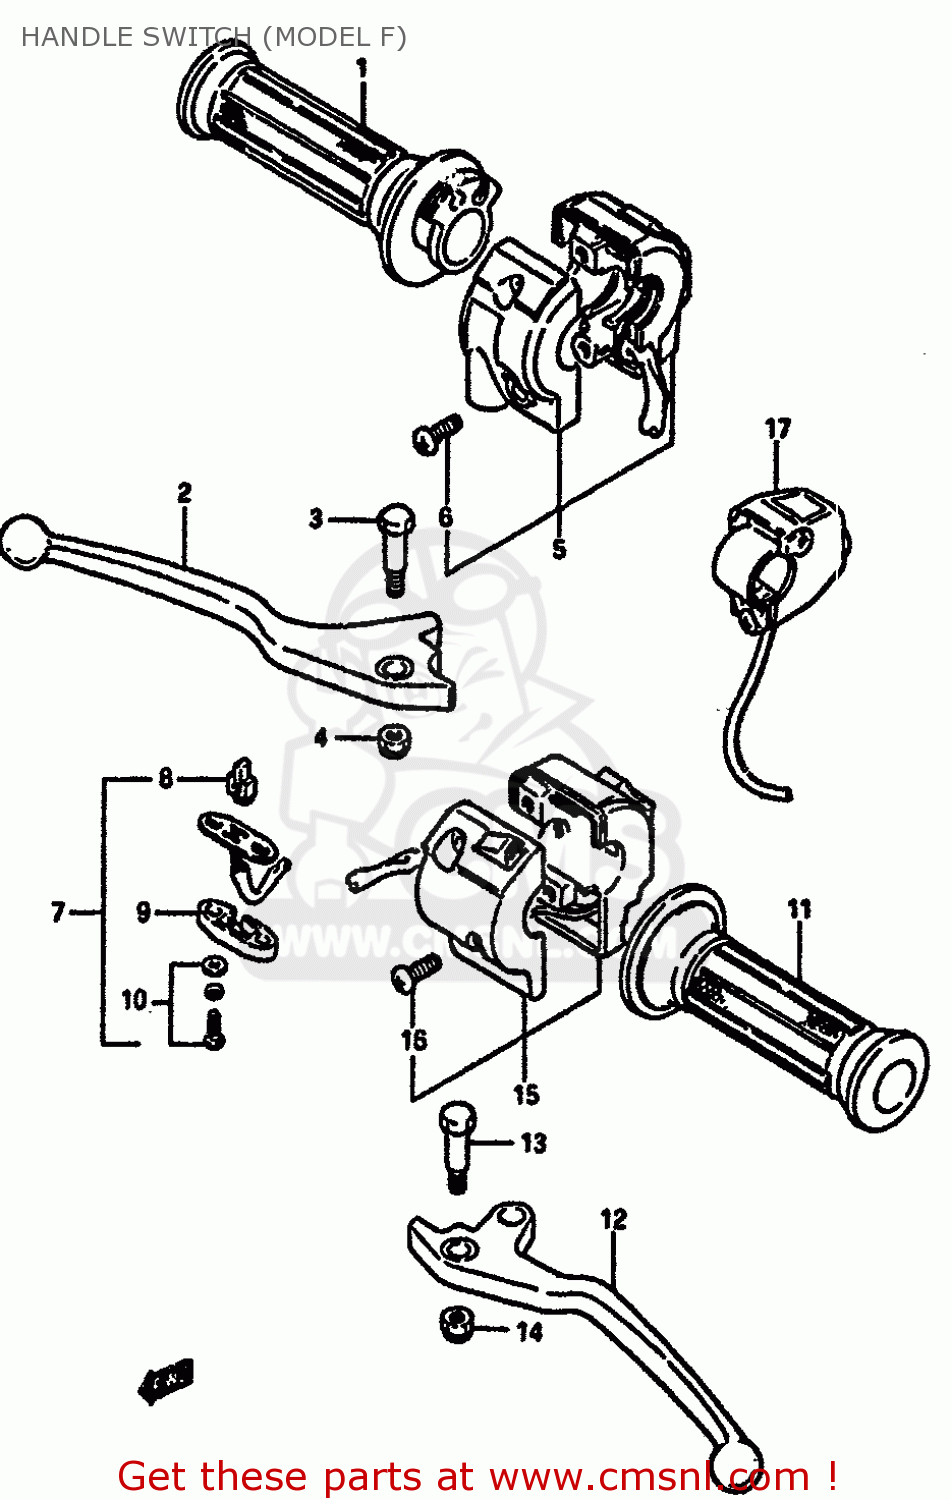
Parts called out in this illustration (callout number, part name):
1	GRIP,THROTTLE
2	LEVER,BRAKE
3	BOLT,LEVER
4	NUT
5	SWITCH ASSY,HANDLE RH
6	SCREW 5X20
7	SWITCH ASSY,STOP
8	CONTACT,SWITCH
9	COVER,FR BK TERMINAL BASE
10	SCREW
11	GRIP,L
12	LEVER,CLUTCH (BLACK)
13	BOLT,LEVER
14	NUT
15	SWITCH ASSY,HANDLE LH
16	SCREW 5X20
17	SWITCH ASSY,LIGHTING
